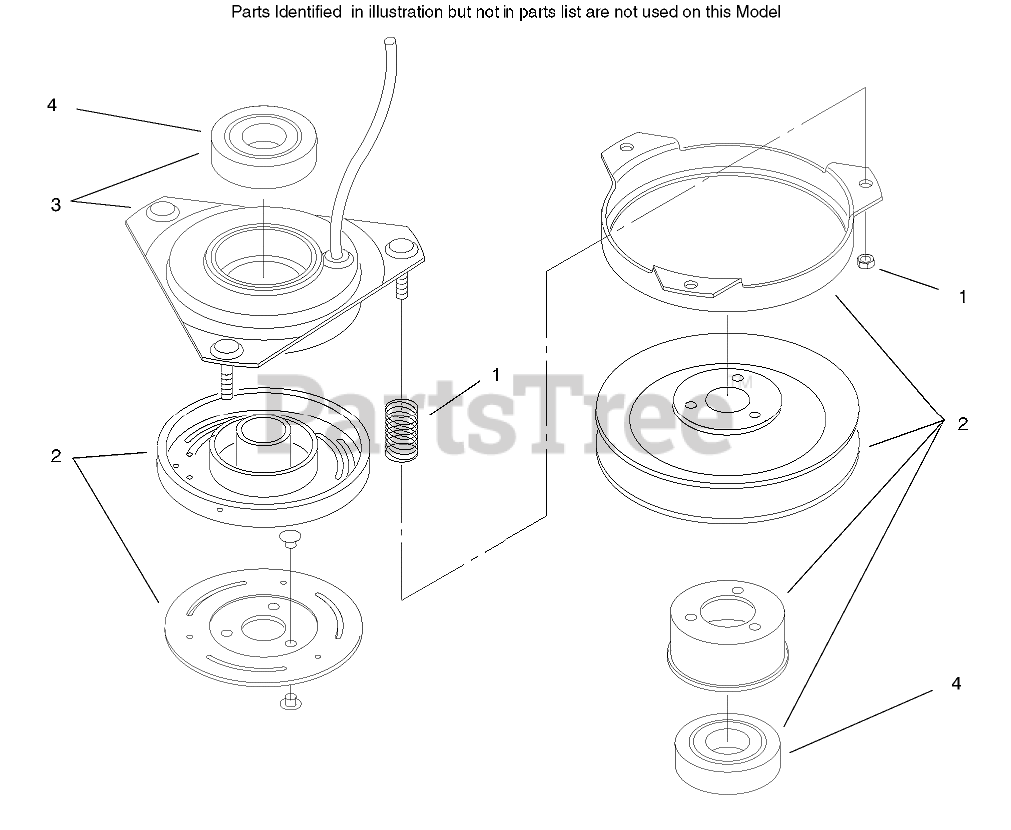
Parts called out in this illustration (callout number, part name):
1	ACCESSORY PKG SRVC PART
2	ASM - ROTOR/ARMATURE
3	FIELD ASSY (SRVC PART)
4	BEARING-ELEC CLUTCH
